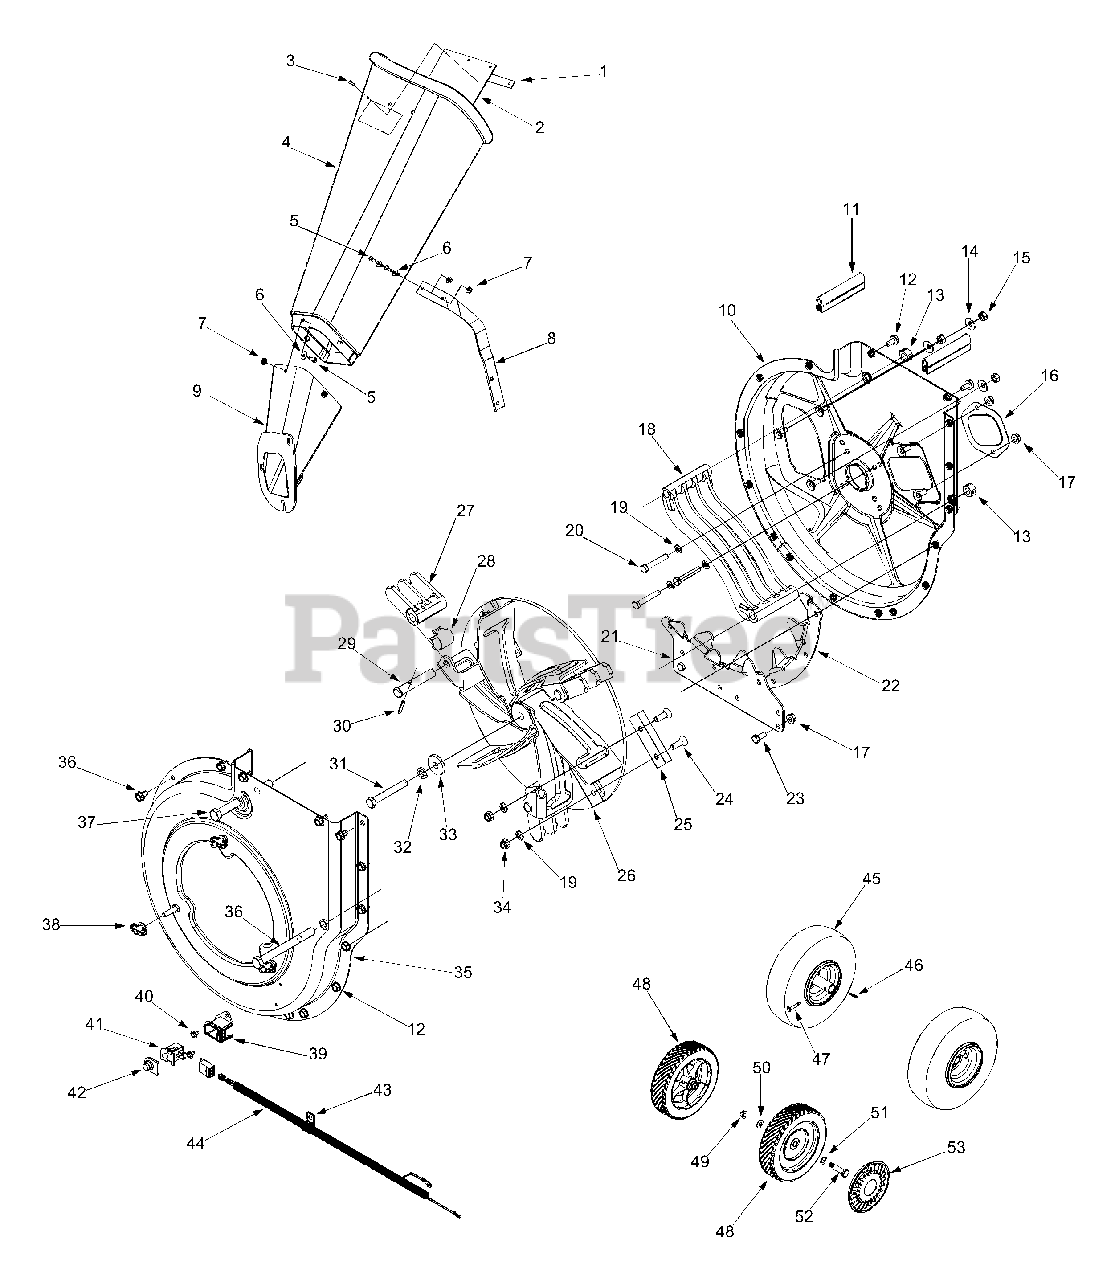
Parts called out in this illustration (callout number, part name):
1	Chute Flap Strip
2	Chute Flap
3	Pop Rivet
4	Chipper Chute
5	Hex Cap Screw 1/4-20 x .620
6	Flat Washer .28 ID x .74 OD
7	Hex Lock Nut 1/4-20
12	Hex Washer Screw 5/16-18 x .60
13	Hex Lock Nut 1/2-13
14	Bell Washer .345 ID x .88 OD
15	Hex Nut 5/16-18
17	Hex Lock Nut 5/16-18
18	Flail Screen
19	Lock Washer 5/16
20	Hex Cap Screw 5/16-24 x 2.0
21	Lower Shredder Blade
22	Upper Shredder Blade
23	Hex Cap Screw 5/16-18 x .75
24	Hex Cap Screw 5/16-24 x 1.0
25	Chipper Blade
26	Impeller Assembly
27	Flail Blade
28	Pin Clip
29	Clevis Pin
31	Hex Cap Screw 3/8-24 x 2.75
32	Lock Washer 3/8
33	Flat Washer 3/8 x 1.25
34	Hex Lock Nut 5/16-24
36	Hex Washer Screw 5/16-18
37	Hex Cap Screw 1/2-13 x 5.0
38	Knob 5/16-18 x .70
39	Safety Switch Mounting Cover
40	Hex Washer Screw #10-16 x .30
41	Snap Mount Switch
42	Switch Cover
43	Clamp
44	Wire Harness
45	Wheel Assembly 10 x 4.0
46	Cotter Pin
47	Clevis Pin
48	Wheel Assembly 8 x 2.0
49	Hex Lock Nut 3/8-16
50	Bell Washer .401 ID x .870 OD
51	Wave Washer .53 ID x .78 OD
52	Shoulder Bolt
53	Hubcap
